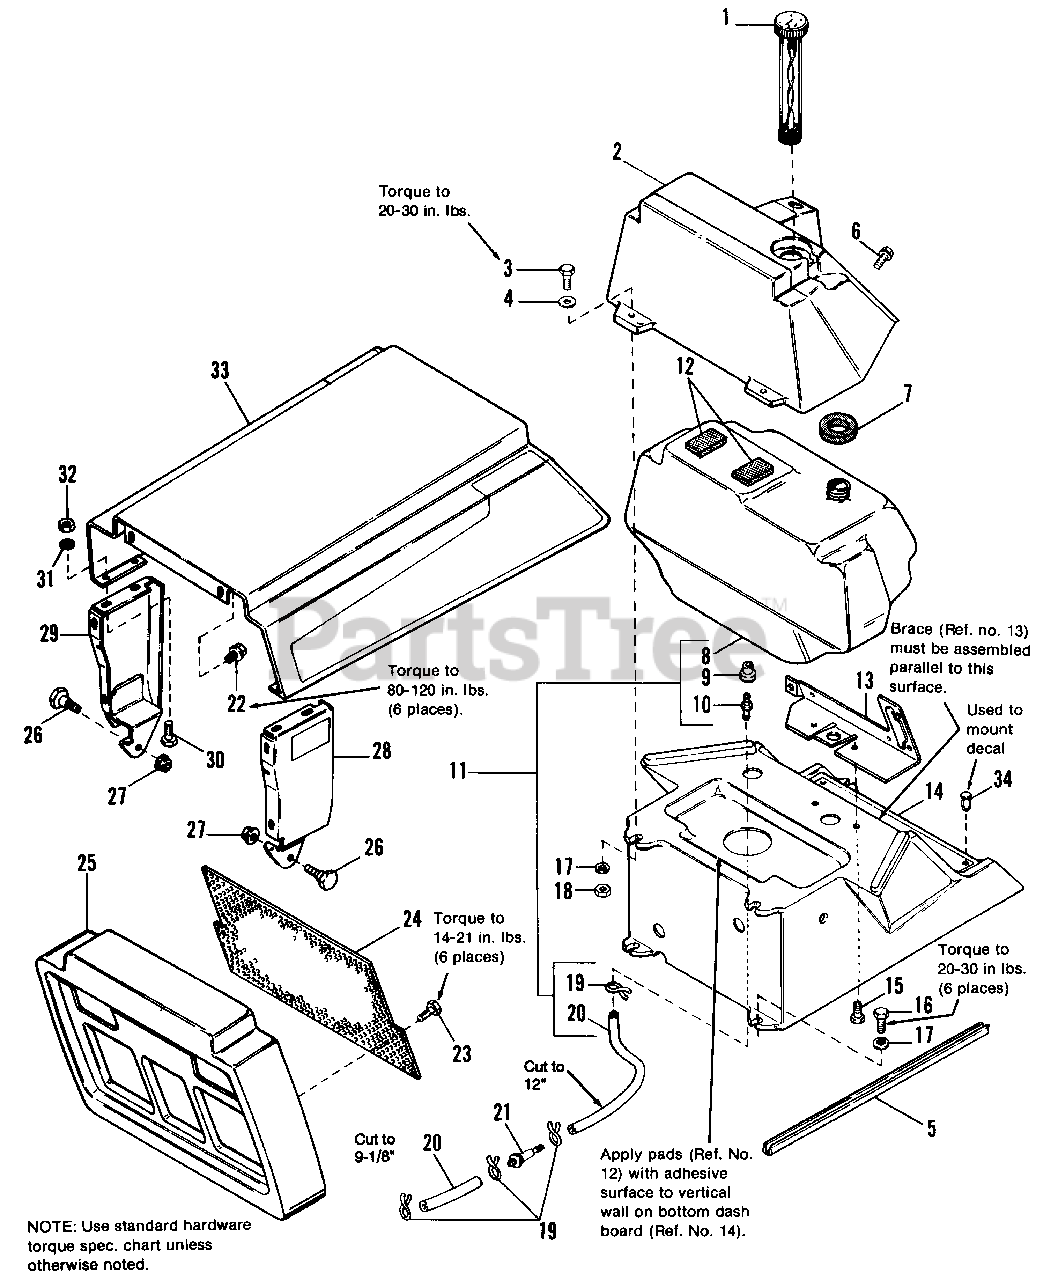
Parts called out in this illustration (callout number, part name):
1	CAP, w/Gas Gauge
2	DASHBOARD, Top
3	CAPSCREW, Hex, 1/4-20 x 1-1/4
4	WASHER, 1/4
5	EDGING, Lower Dash
6	SCREW, Hex Washer Hd., 1/4-14 x 5/8
7	WASHER, Foam
11	TANK ASSY., Fuel (Ref. No. 11 Incl. Ref. Nos. 8, 9, 10, 19 Qty. 1 & 20)
14	DASHBOARD, Bottom
15	SCREW, Taptite, 1/4-20 x 3/4
16	SCREW, Taptite, 1/4-20 x 1
17	LOCKWASHER, Dish, 1/4
18	LOCKNUT, Hex, 1/4-20
19	CLAMP, Hose
20	HOSE, Fuel, 45" long (Cut toHOSE, Fuel, Cut to 12th needed-See notes on page 28)
21	FILTER, Fuel
22	SCREW, Plastite, 1/4 x 1
23	SCREW, Plastite, #10-14 x 1/2
25	GRILLE (Incl. Ref. No. 35)
26	BOLT, Shoulder, 5/16-18 x 7/8
27	LOCKNUT, Flange, Whiz, 5/16-18
28	PANEL ASSY., L.H.
29	PANEL ASSY., R.H.
30	CAPSCREW, Hex, 1/4-20 x 1/2
31	LOCKWASHER, 1/4
32	NUT, Hex, 1/4-20
34	CLIP, Canoe
